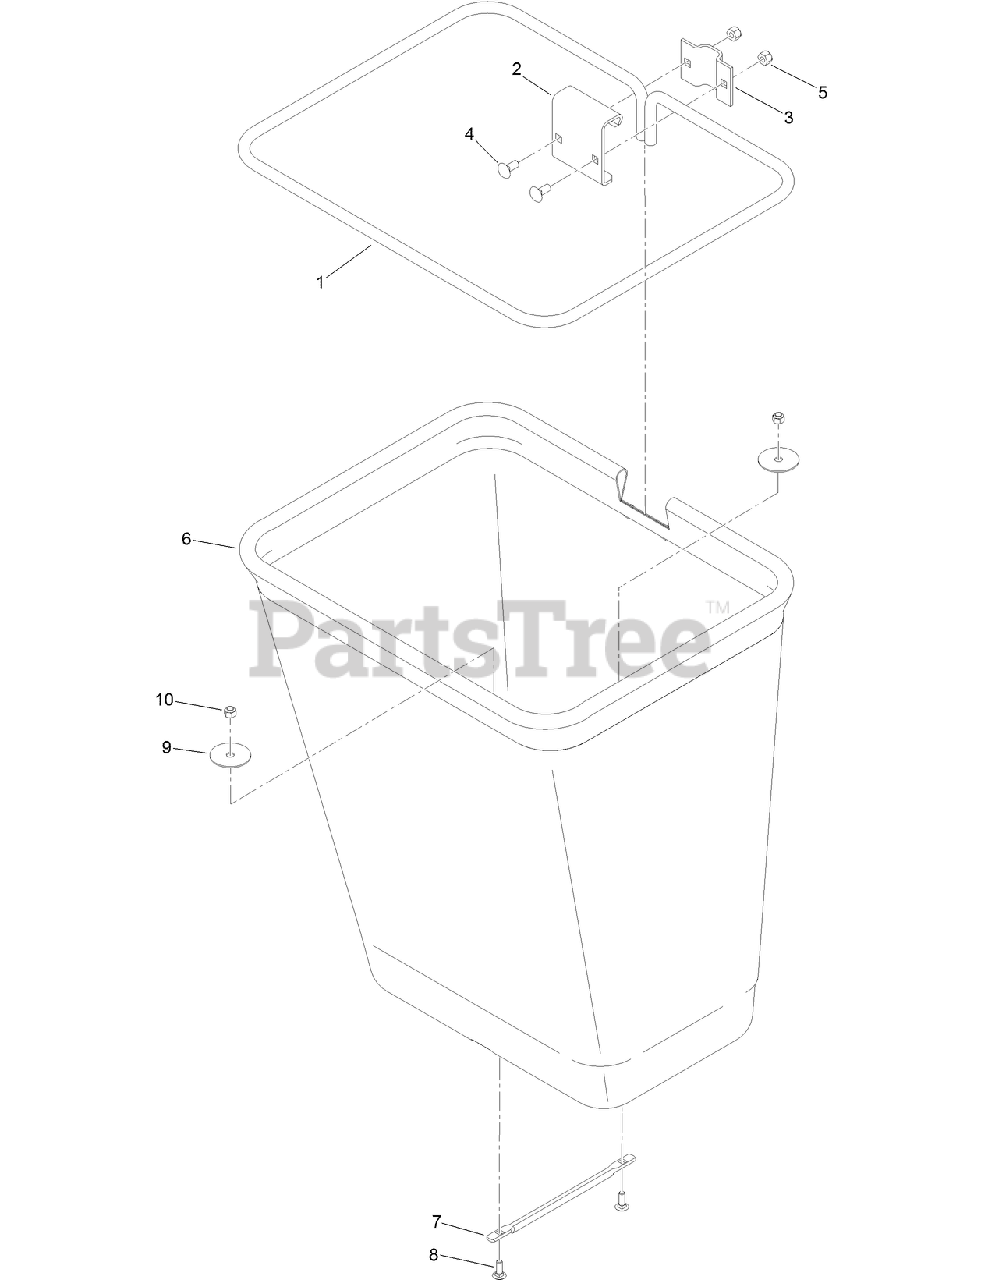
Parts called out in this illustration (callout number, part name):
1	FRAME-BAG
2	HANGER-BAG
4	BOLT-CARR
5	NUT-LOCK, NI
7	HANDLE-BAG
8	BOLT-CARR
9	WASHER
10	NUT-LOCK, NI
